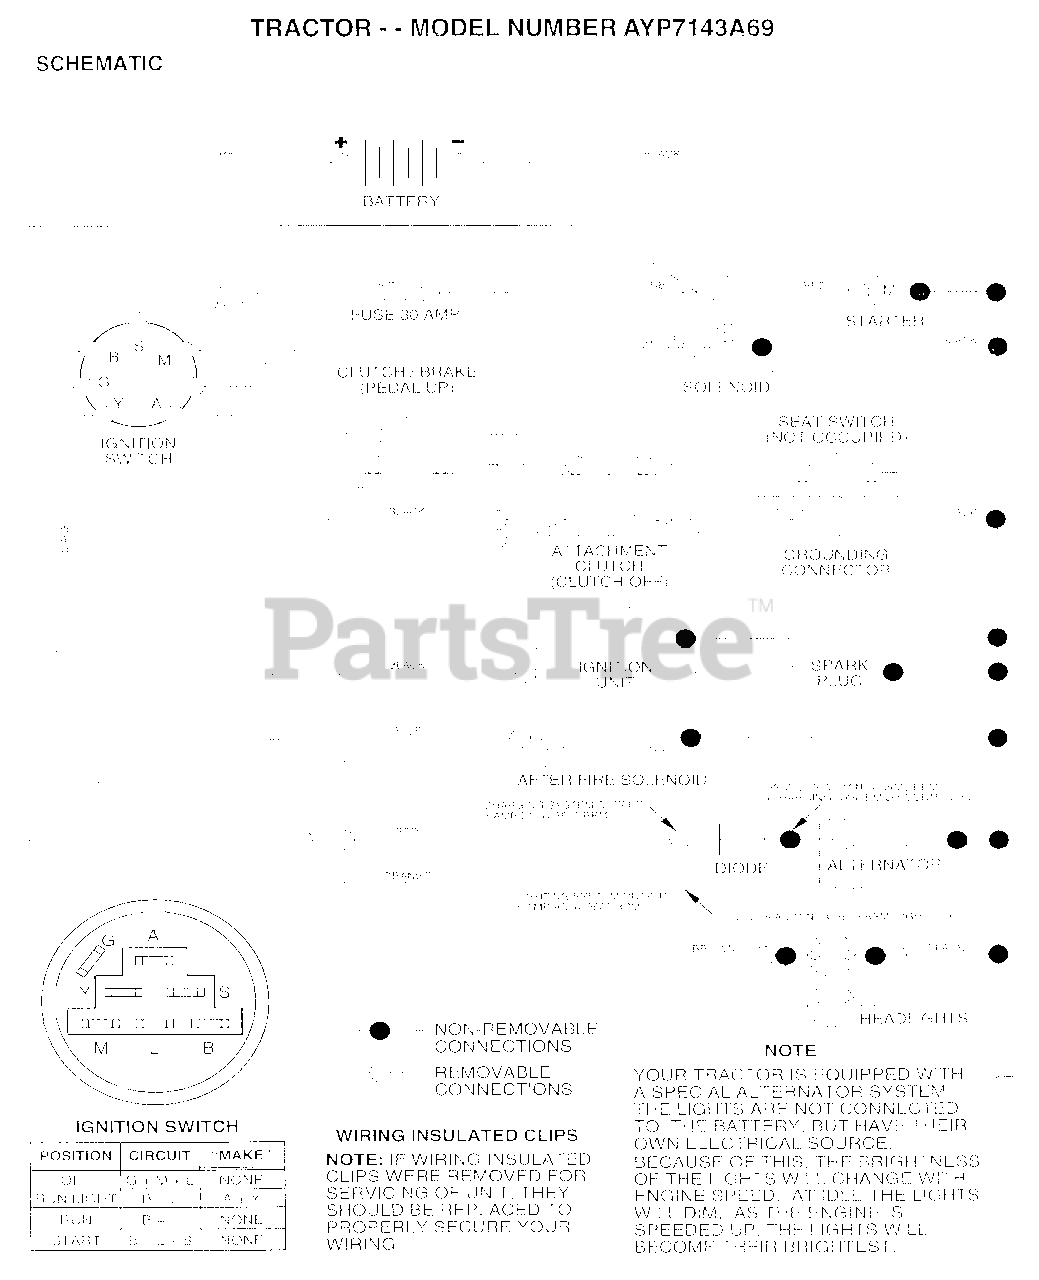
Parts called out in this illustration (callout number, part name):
2	BOLT LT
3	WASHER
4	LOCKWASHER
7	TUBE T
9	HOSE CLAMP T
15	FASTNER.SNAP-IN
20	NUT
21	"HARNESS,LIGHT SOC"
22	HEADLAMP BULB
24	"CABLE T, BATTERY"
25	CABLE.BTRY.6GA.RD
26	FUSE HYT
28	CABLE T
29	SWITCH SEAT
30	SWITCH IGN 4POS
31	NUT IGNITION
32	COVER KEY SWITCH
33	KEY
35	BRACKET LT
36	SCREW
38	BRACKET SWITCH IN
39	SWITCH INTERLOCKT
41	BOLT HXHD FIN
44	NUT HXKEP 1/4X20
48	ADAPTER AMMETER
52	PROTECTION LOOP
70	HARNESS ENGINE
